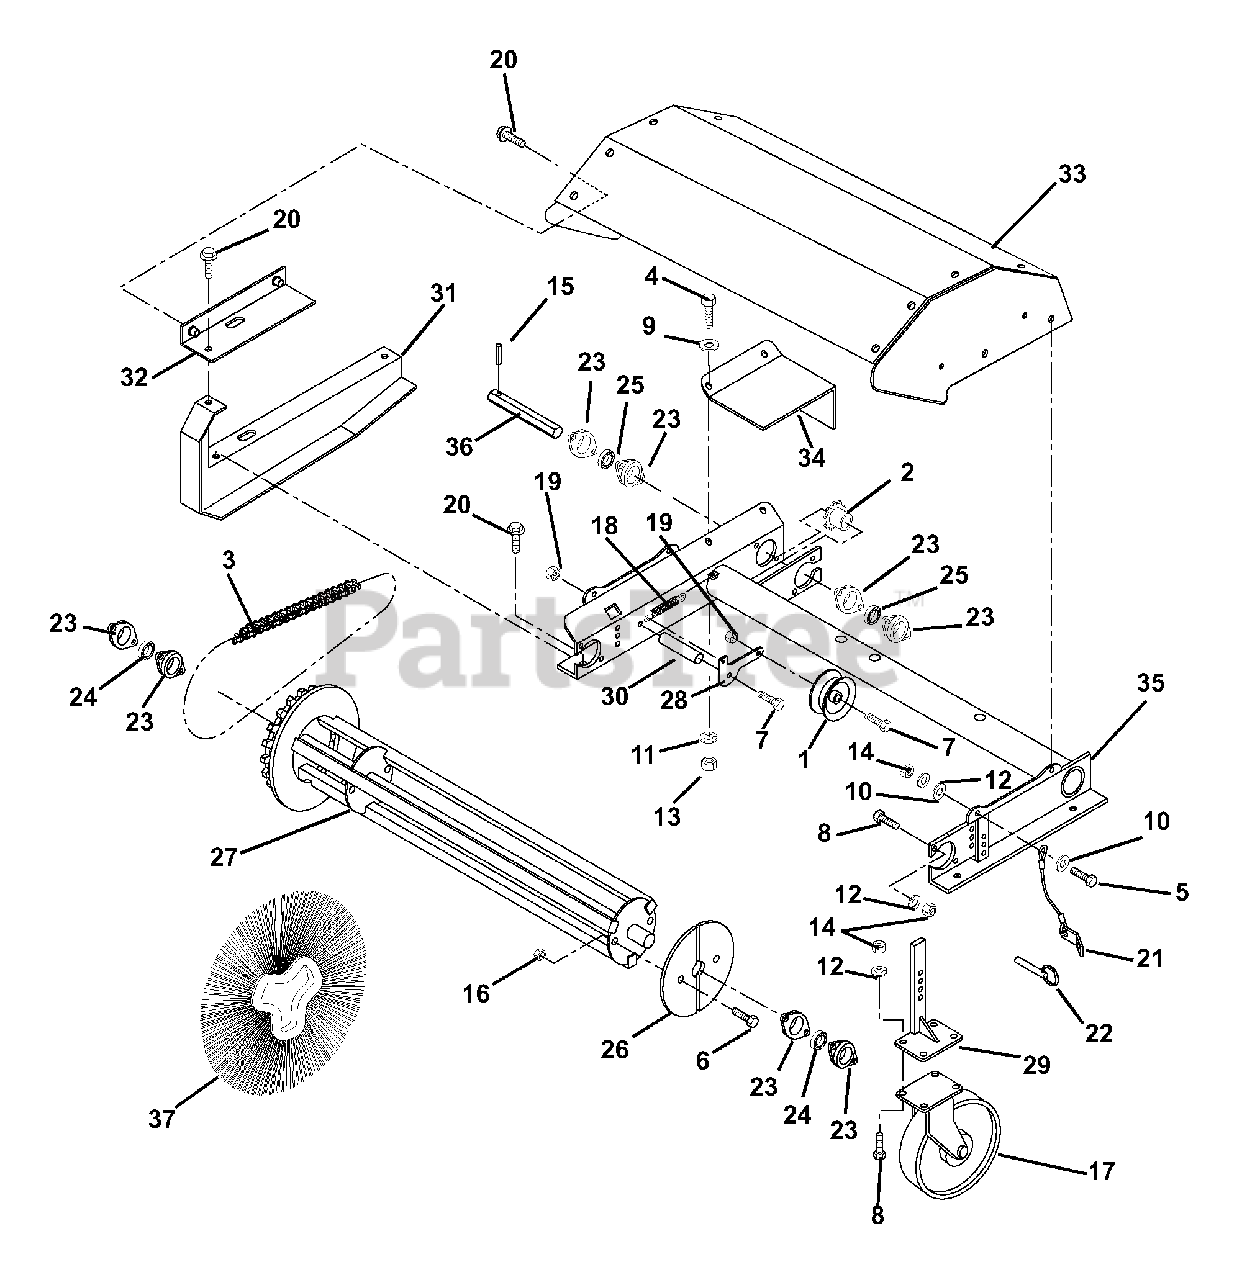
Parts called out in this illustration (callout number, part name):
1	CHAIN TIGHTENER
2	SPROCKET
3	CHAIN, ASS'Y #40X106 EDLS W/LK
4	@BLT-HEX .25-20X.75 GR5 YWZC
5	@BLT-HEX .31-18X1.00 GR5 YWZC
6	@BLT-HEX .31-18X2.25 GR5 YWZC
7	@BLT-HEX .38-16X1.50 GR5 YWZC
8	@BLT-HEX .31-18X.75 GR5 YWZC
9	@WSHR-FL-STL.281X.62X.065 YWZC
10	@WSHR-FL-STL.312X.734X.065 YWZ
11	@WSHR-LK .25X.062 REG YWZC
12	@WSHR-LK .31X.078 REG YWZC
13	@NUT-HEX .25-20 YWZC
14	@NUT-HEX .31-18 YWZC
15	PIN, SPRING LOK .187 X 1.25
16	NUT, LOK STAMPED .312-18 TINN.
17	WHL, 5 DIA.
18	SPRING, TENSION .50 X 3.0
19	@NUT-LK-CTR .38-16 YWZC
20	SCREW, GR 10.9 M6X1-20
21	LANYARD,.06 CAB.1.25X6,TYP C
22	PIN, HITCH, .38 X 2
23	FLANGE, SPHERICAL 2"
24	BRG 1.00 BORE, SPHER. OD.
25	BRG-BALL .884HEXX52MMX1.07
26	RETAINER PLATE (SET OF 2)
27	WELD, CORE C36TW
28	ARM, IDLER,BRM C36TW
29	WELD, CASTER LEG, C36TW
30	BSHG, .62X12 GA X.75
31	SHIELD,CHAIN, ARIENS
32	SHIELD, CHAIN,TOP,ARIENS
33	KIT, HD, ARIENS
34	SHIELD, INPUT, ARIENS
35	WELD, BFRM,ARIENS
36	SHAFT, HEX 20.5, W/HOLE
37	SET,SECTION,24",P,CONV.
